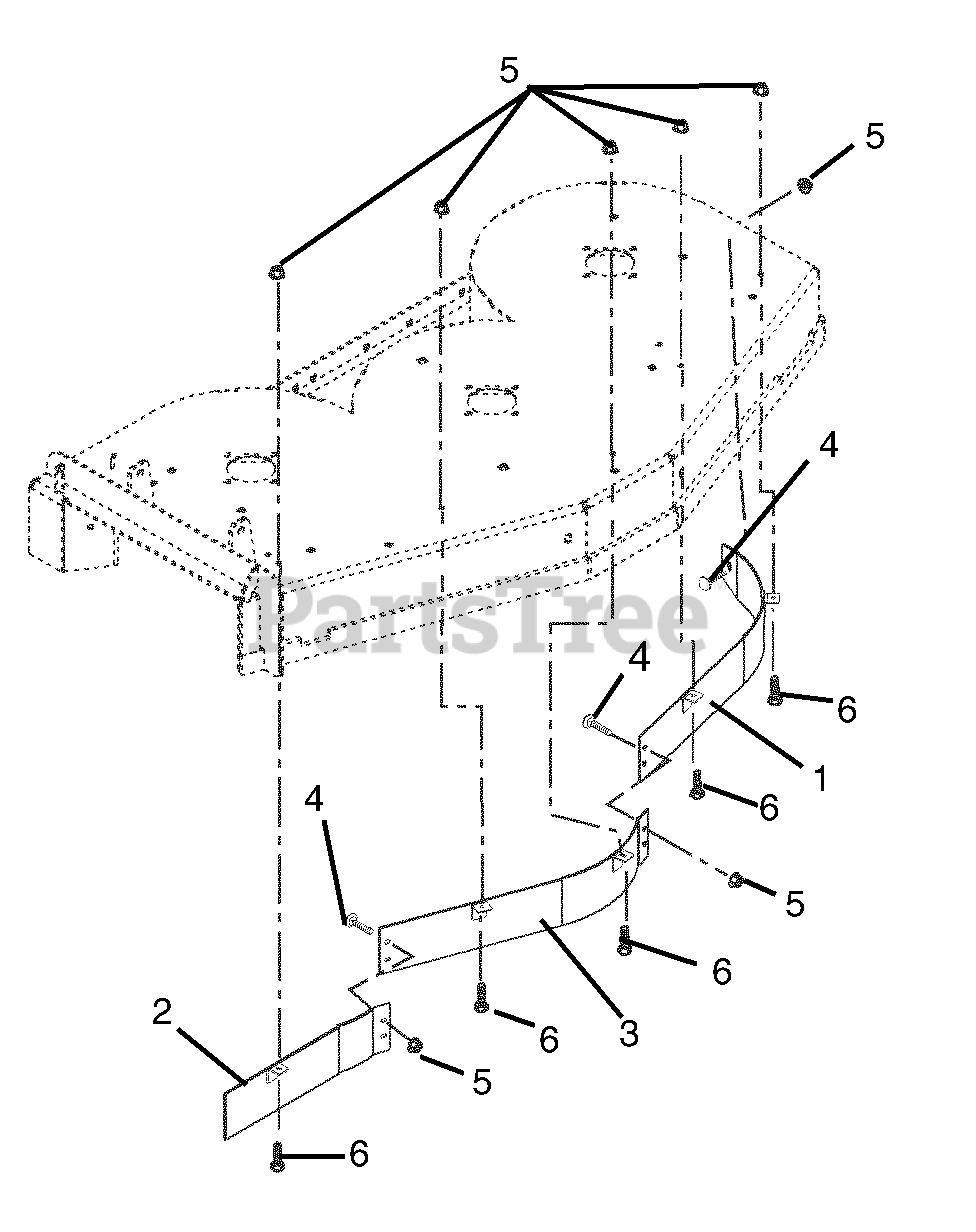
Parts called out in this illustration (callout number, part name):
1	BAFFLE-BAHIA-LEFT FRONT-48"
2	BAFFLE-BAHIA-RIGHT FRONT-48"
3	BAFFLE-BAHIA-CENTER FRONT-48"
4	@BLT-RDHDSQNK .31-18X.75 G5YZ
5	@NUT-LK-TOP-FLG .31-18 YWZC
6	@BLT-HEX .31-18X.75 GR5 YWZC
